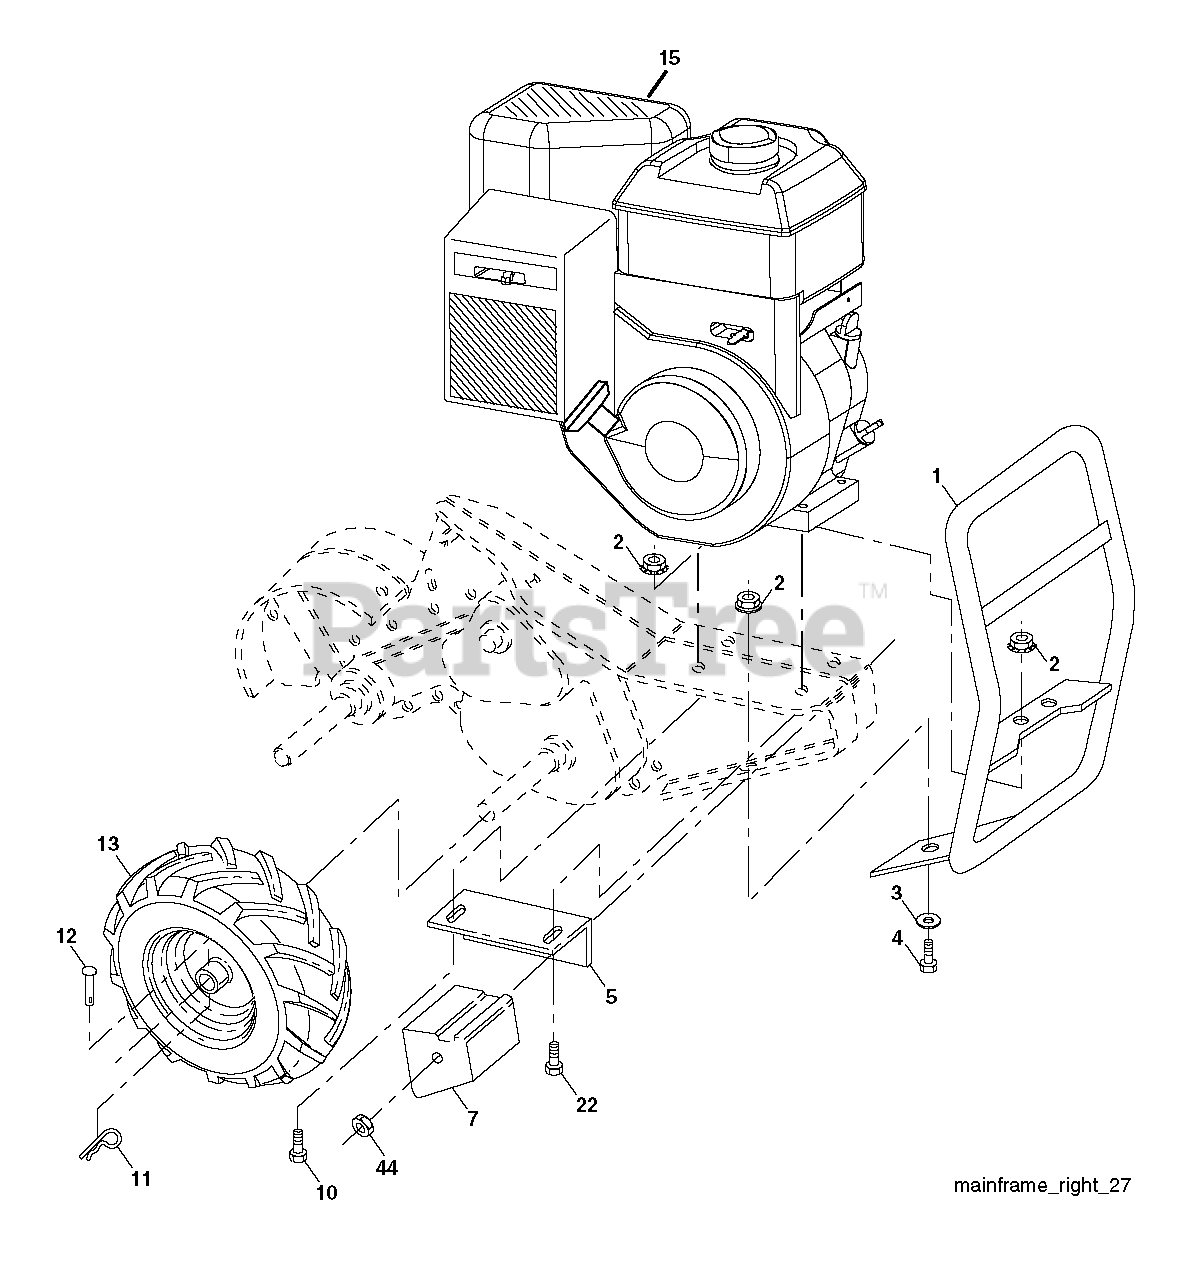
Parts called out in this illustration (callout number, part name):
1	RP.BUMPER.ASM.TILLER.
2	LOCKNUT-FLANGE 5/16-18
3	WASHER
4	BOLT
5	BRACKET RH CRT
7	COUNTERWEIGHT, RH
10	BOLT
12	RIVET,DRILLED
13	TIRE.16X4-8.CHEVRON.TILLER
15	Poulan TBD
22	BOLT, HEX 5/16-18X1-3/4
44	BOLT, HEX 5/16-18X1-3/4
